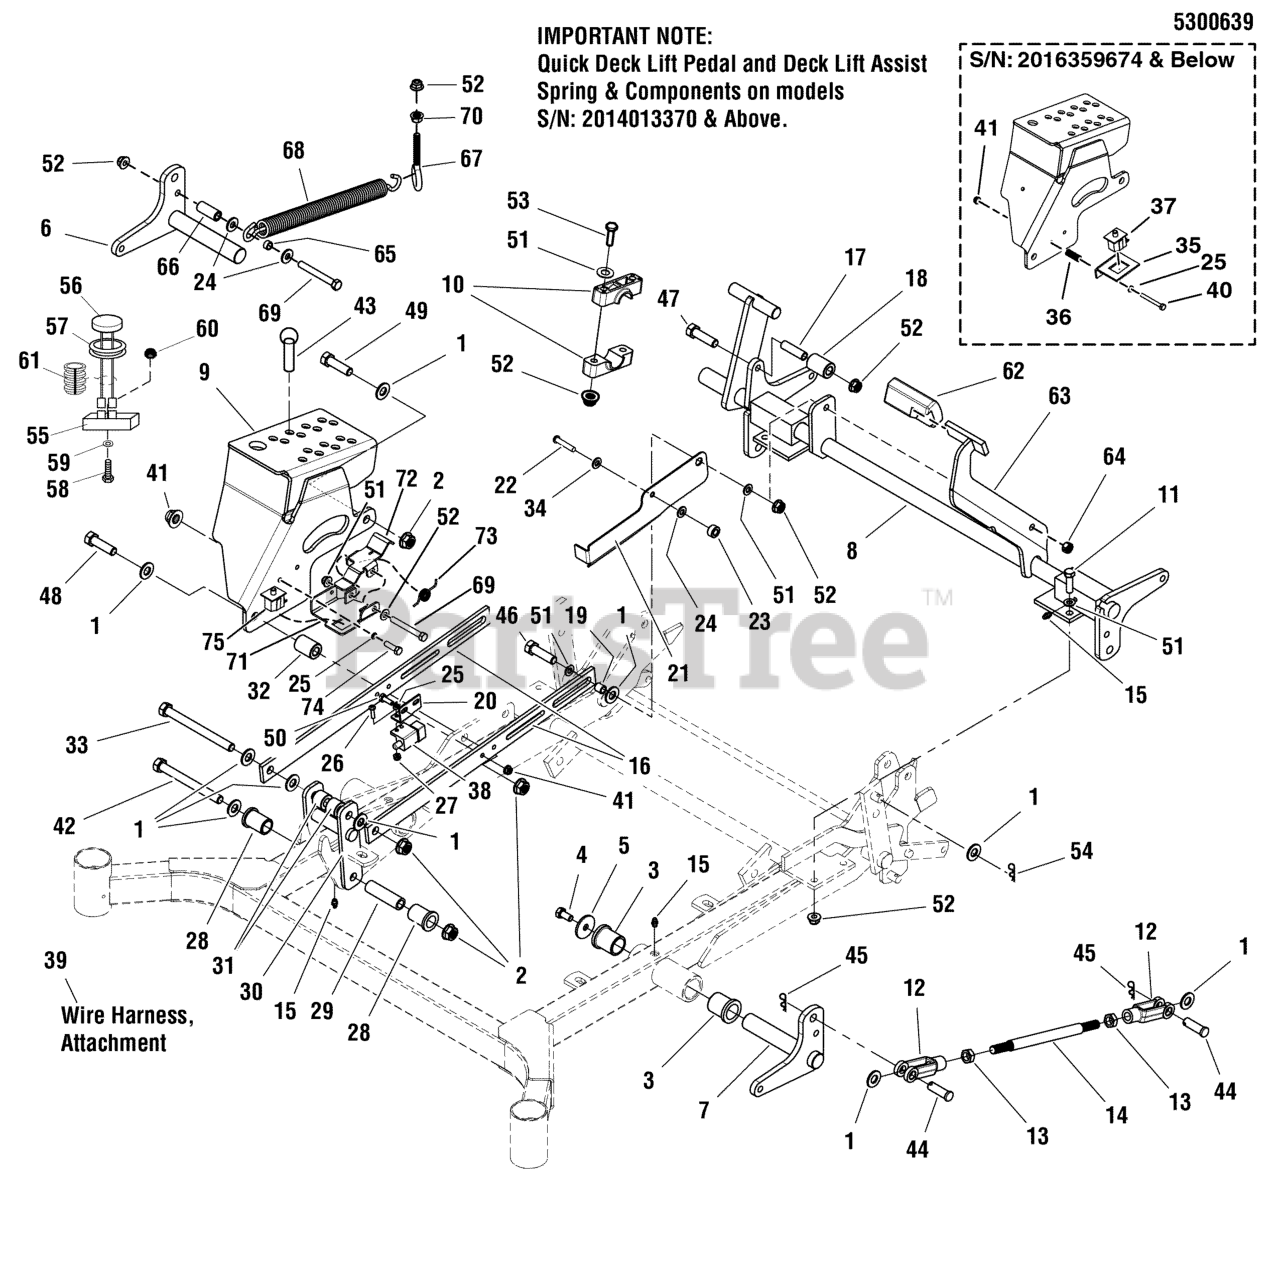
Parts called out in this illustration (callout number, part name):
1	WASHER, 1/2 SAE
2	NUT, Hex Flange, Nylock, 1/2-13
3	BUSHING, FLANGE
4	BOLT, 3/8-16 X 3/4, GD5, YZ WITH PATCH
5	WASHER, .390 X 1.50 X .109, YZ
6	WELD., DECK LIFT LEVER - RH - RED
7	WELD., DECK LIFT LEVER - LH - RED
8	WELD, DECK LIFT SHAFT - OUTFRONT - RED
9	WELD, CUT HEIGHT BOX - RED
10	PIVOT BLOCK, PLASTIC
11	BOLT, 3/8-16 X 1-1/4" GD5 CZ
12	CLEVIS, 1/2-20, STEEL
13	NUT, 1/2-20 HEX JAM
14	ROD, DECK LIFT, OUTFRONT
15	GREASE FITTING, 1/4-28 STRAIGHT
16	BAR, ACTUATOR LINK - RED
17	SPACER, .38 X .50 X 1.78 YZ
18	SPACER, .51 X 1.00 X 1.47 YZ
19	SPACER, .38 X .50 X .50, YZ
20	PLATE, SWITCH MOUNT - RED
21	PLATE, SWITCH COVER - RED
22	PIN-CLEVIS, 5/16 X 1 YZ
23	COLLAR, 5/16 SET
24	WASHER, 5/16 USS
25	WASHER, 1/4 SAE
26	SCREW, #10-24 X 3/4 ROUND PHILLIPS
27	NUT, #10-24 HEX NYLON LOCK
28	BUSHING, FLANGED, 3/4 X 1 X 1
29	SPACER, .51 X .75 X 2.66
30	WELD, PIVOT LINK - ACTUATOR - RED
31	SPACER, .52 X 1.00 X .75
32	SPACER, .52 X 1.00 X 1.38 YZ
33	BOLT-1/2-13 X 5 GD5 YZ
34	WASHER, 5/16" SAE
35	MOUNT, LOW PROFILE SWITCH - RED
36	SPRING, .325 X .475 X 1.25, BLK E-COAT
37	SWITCH, LOW PROF, NC/NO
38	SWITCH, PLUNGER, N.O./N.C.
39	WIRE HARNESS, ATTACHMENT, DECK
40	BOLT, 1/4-20 X 2-1/4, GD5
41	NUT, 1/4-20 HEX NYLOCK FLANGE
42	BOLT, 1/2-13 X 4" GD5 CZ
43	PIN-COTTERLESS
44	CLEVIS PIN, 1/2 X 1.36 SAE STANDARD
45	PIN, COTTER, 1/8 X 3/4
46	BOLT, 3/8-16 X 1-1/2" GD5 CZ
47	BOLT, 3/8-16 X 2-3/4" GD5 CZ
48	BOLT, 1/2-13 X 2-3/4 GD5 CZ
49	BOLT, 1/2-13 X 1-1/2 GD5 CZ
50	BOLT, 1/4-20 X 3/4 GD5 YZ
51	WASHER, 3/8 SAE
52	NUT, 3/8-16 HEX NYLOCK FLANGE
53	BOLT, 3/8-16 X 2-1/2" GD5 CZ
54	PIN, HAIR, .0915 X 1-7/8
55	FLASHER, 90 FPM, OUT FRONT MOWER
56	INDICATOR LAMP, RED, LED
57	GROMMET, 1/2
58	BOLT, 1/4-20 X 1-1/2, GD5
59	WASHER, 1/4 SAE
60	NUT, 1/4-20 HEX NYLOCK FLANGE
61	WIRE LOOM, 3/8 ID X 7" LONG
62	PEDAL, Rubber
63	WELD, QUICK DECK LIFT PEDAL - RED
64	NUT, 3/8-16 HEX SIDE LOCK
65	SPACER, .38 X .50 X .27
66	SPACER, .39 X .63 X 1.50
67	EYEBOLT, 3/8-16 X 4, 2.13THRD, .75EYE, C
68	SPRING, DECK LIFT ASSIST
69	BOLT, 3/8-16 X 3" GD5 CZ
70	NUT, 3/8-16 HEX SERRATED FLANGE
71	WELD, SWITCH MOUNT - BLK
72	INDICATOR, DECK POSITION - BLK
73	SPRING, TORSION, .591ID X .40LG X .095WR
74	BOLT, 1/4-20 X 1" GD5 CZ
75	SWITCH, LOWER PRO, NC/NC
